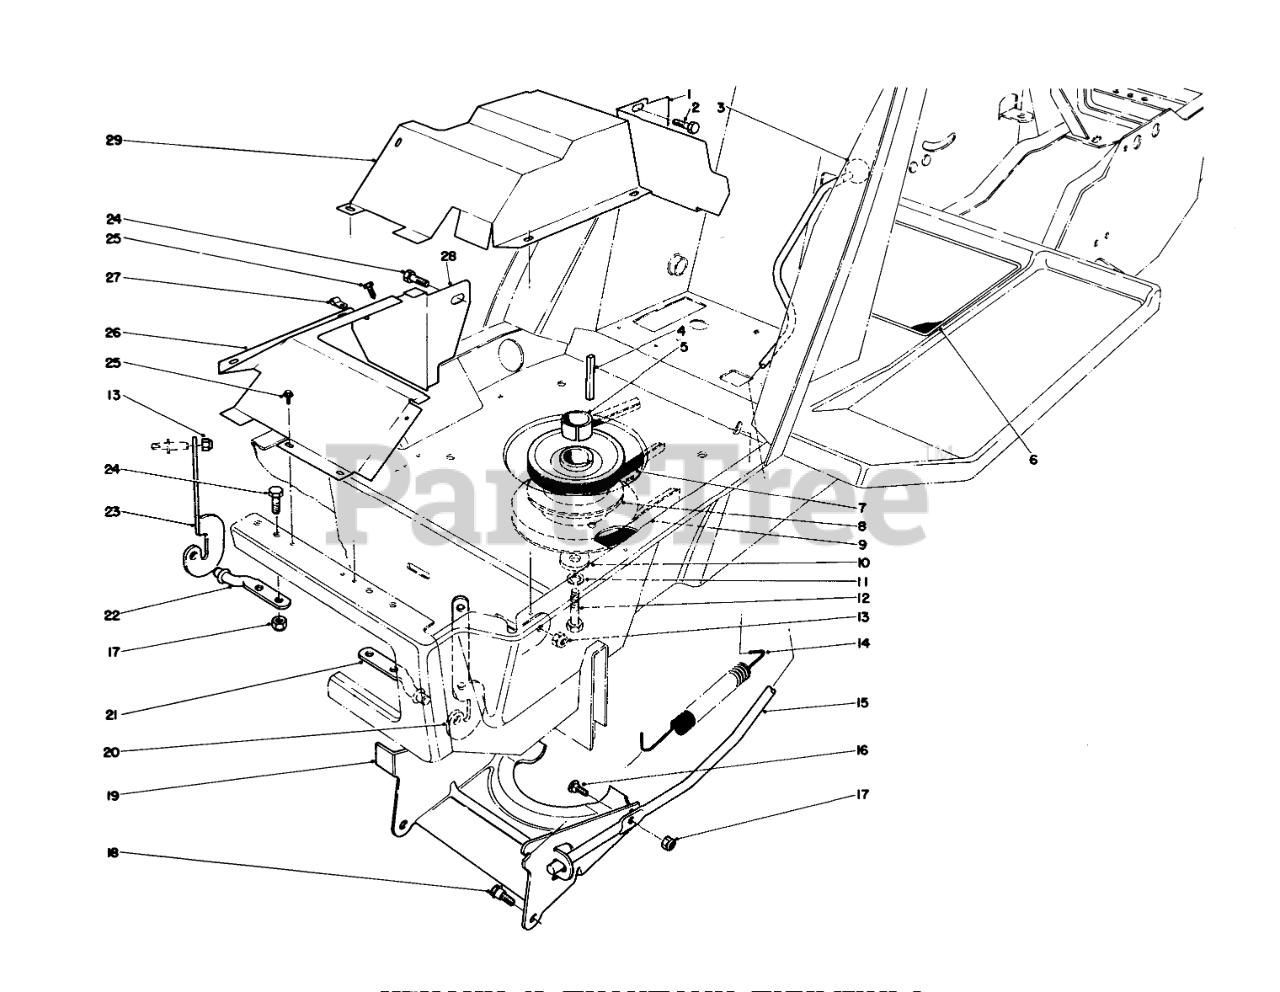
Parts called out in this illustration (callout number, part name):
1	EXH SHIELD SUPT B
2	SCREW-HH
4	KEY-SQUARE
5	PULLEY SPACER
6	OPERATION DECAL
7	V BELT
8	Clutch & Brake-Deck
9	V BELT
10	WASHER
11	WASHER-LOCK
12	SCREW-HH
13	NUT-LOCK, CONE
14	TRACTION SPRING
15	Engagement Lever
16	Bolt
17	NUT-LOCK, CONE
18	SCREW-SHOULDER
19	Actuator-Clutch
20	L.H. HINGE BRACKET
21	LH HOOD HINGE PIN
22	RH HOOD HINGE PIN
23	RH HINGE BRKT
24	SCREW-HH
25	SCREW-HWHTF
26	Heat Shield (Model #57351)
27	CABLE CLAMP
28	Support Heat Shield
29	Heat Shield (Model #57351)
